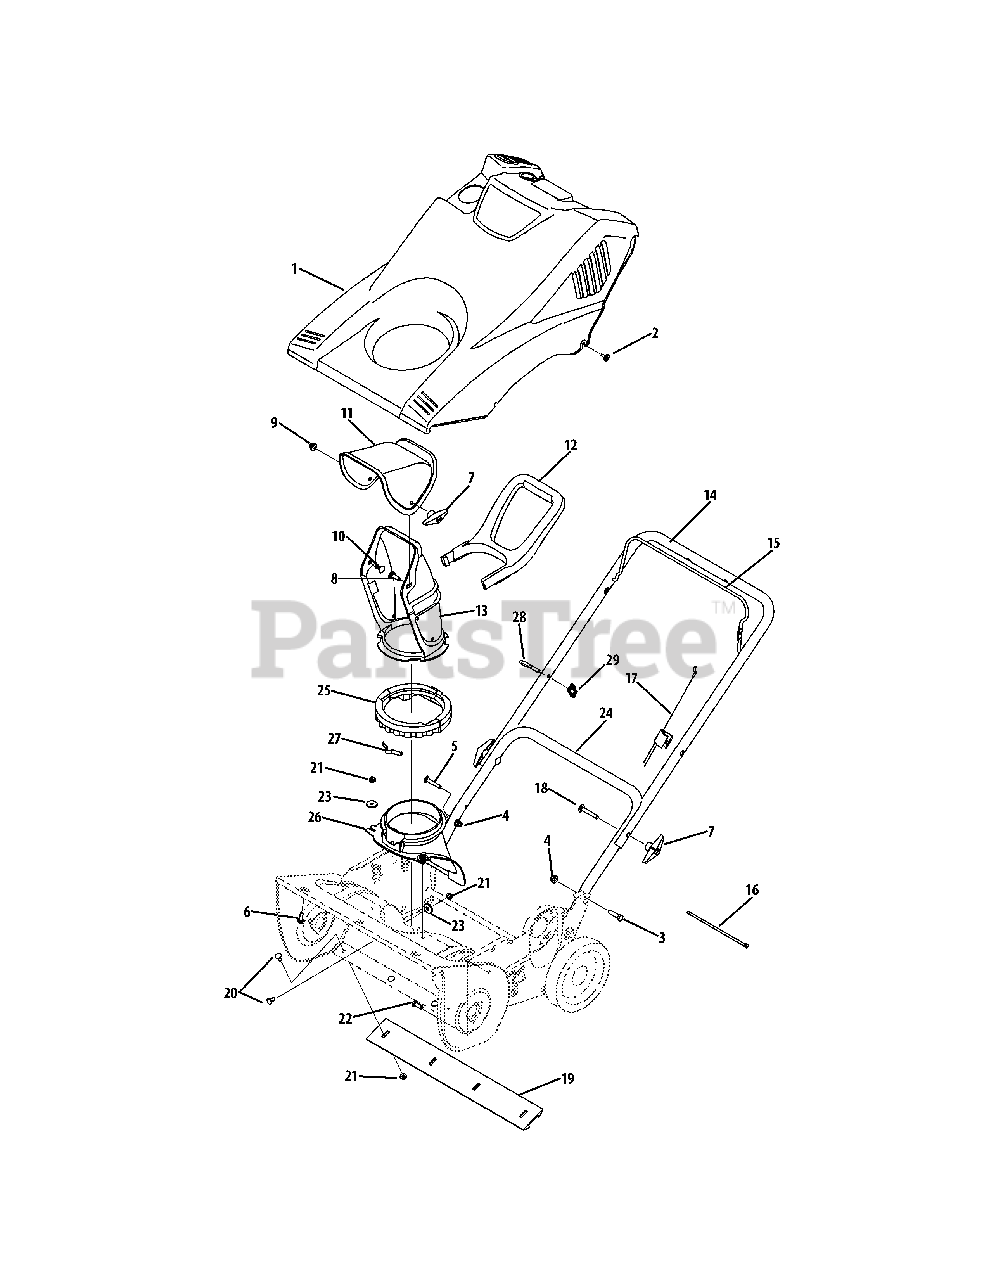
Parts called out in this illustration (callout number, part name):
1	Shroud
2	Hex Screw, 10-16 x .625
3	Hex Flange Screw, 5/16-18 x 1.25
4	Flange Lock Nut, 5/16-18
5	Hex Flange Screw, 5/16-18 x 1.50
6	Hex Screw, 1/4-15 x .750
7	Wing Nut, 5/16-18
8	Carriage Bolt, 5/16-18 x 1.00
9	Flange Lock Nut, 5/16-18
10	Carriage Bolt, 5/16-18 x .750
11	Upper Chute
12	Chute Handle
13	Lower Chute
14	Upper Handle
14	Gullwing Handle
15	Bail Control
15	Gullwing Control Bail
16	Cable Tie, 3/16 x .05 x 7.4
17	Clutch Cable
18	Carriage Bolt, 5/16-18 x 2.00
19	Shave Plate, 21"
20	Carriage Screw, 1/4-20 x .62
21	Flange Lock Nut, 1/4-20
22	Hex Screw, 5/16-18 x .75
23	Flat Washer, .265 x .938 x .120
24	Lower Handle
25	Lower Chute Ring
26	Chute Adapter
27	Chute Adjustment Spring
28	Eye Bolt, 1/4-20
29	Knob Handle
